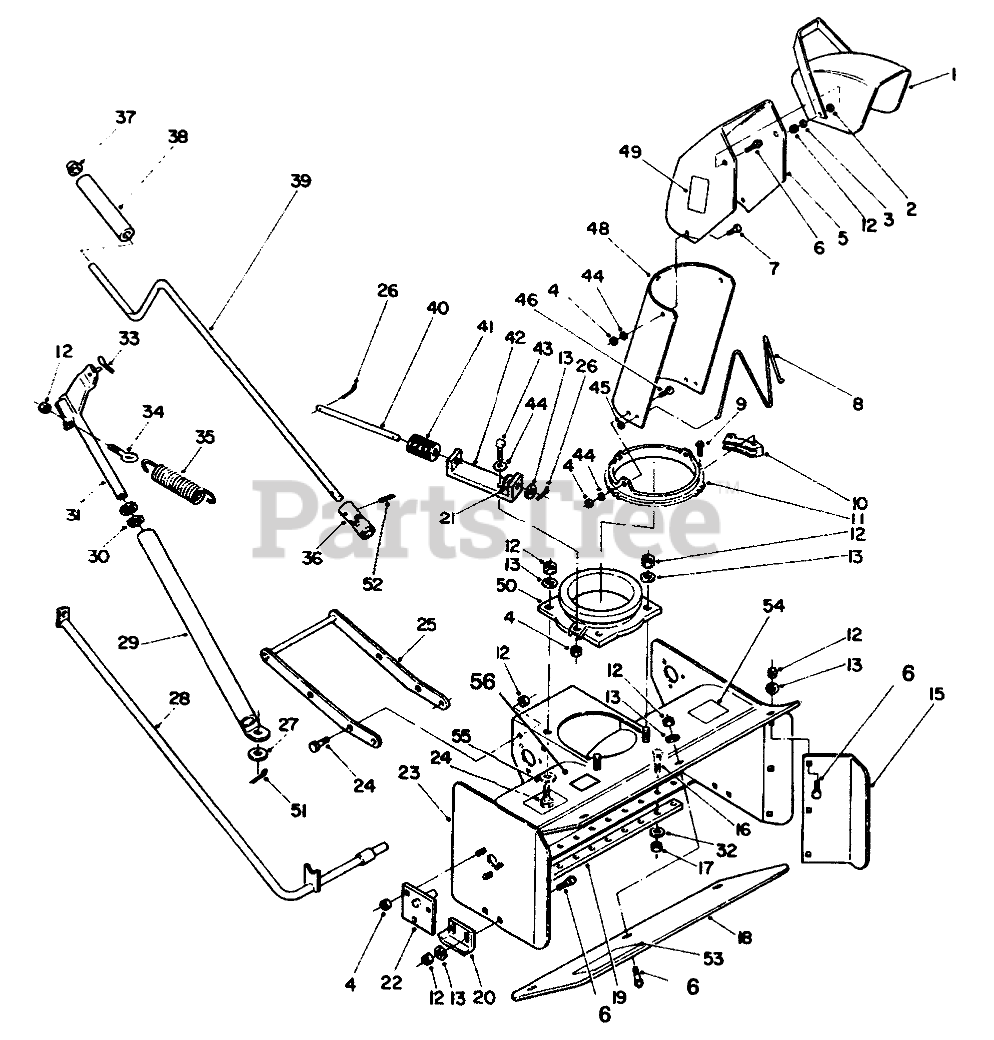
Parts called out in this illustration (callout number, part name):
1	Deflector
2	WASHER-RUBBER
3	WASHER-BELLEVILLE
4	NUT-LOCK, NI
5	Chute-Upper Discharge(Incl. Ref. #49 pg.2)
6	BOLT-CARR
7	SCREW-HH
8	WIRE-CHUTE
9	SCREW-SPECIAL
10	RETAINER-CHUTE
11	CHUTE SWIVEL RING
12	NUT-LOCK, NI
13	WASHER-FLAT
15	PLATE-EXTENSION, RH
16	SCREW-CARR
17	NUT-LOCK, NI
18	PLATE-EXTENSION
19	SCRAPER-REVERSIBLE
21	WASHER-SPRING
22	SUPPORT
23	AUGER W/DECALS ASM
24	SCREW-HH
25	Frame-Mounting
26	PIN-COTTER
27	WASHER-FLAT
28	SUPPORT,ROD
29	SNOW THROWER COM PKG
30	WASHER-FLAT
31	LIFT ROD ASM
32	WASHER-FLAT
33	Hairpin Cotter
34	EYEBOLT
35	SPRING
36	Universal
37	RETAINER-PUSH ON
38	GRIP-CONTROL, CHUTE
39	ROD-CHUTE CONTROL
41	GEAR-WORM, CHUTE
42	BRACKET-WORM RED
43	BOLT-CARR
44	WASHER-PLAIN
45	NUT-PUSH
46	BOLT-CARR
48	EXTENDER-CHUTE, UPPER
49	Decal-Danger
50	ADAPTER
51	PIN-COTTER
52	PIN-SPRING
53	DECAL-ATTACHMENT
54	DECAL-DANGER
55	Washer
56	DECAL-WARNING
